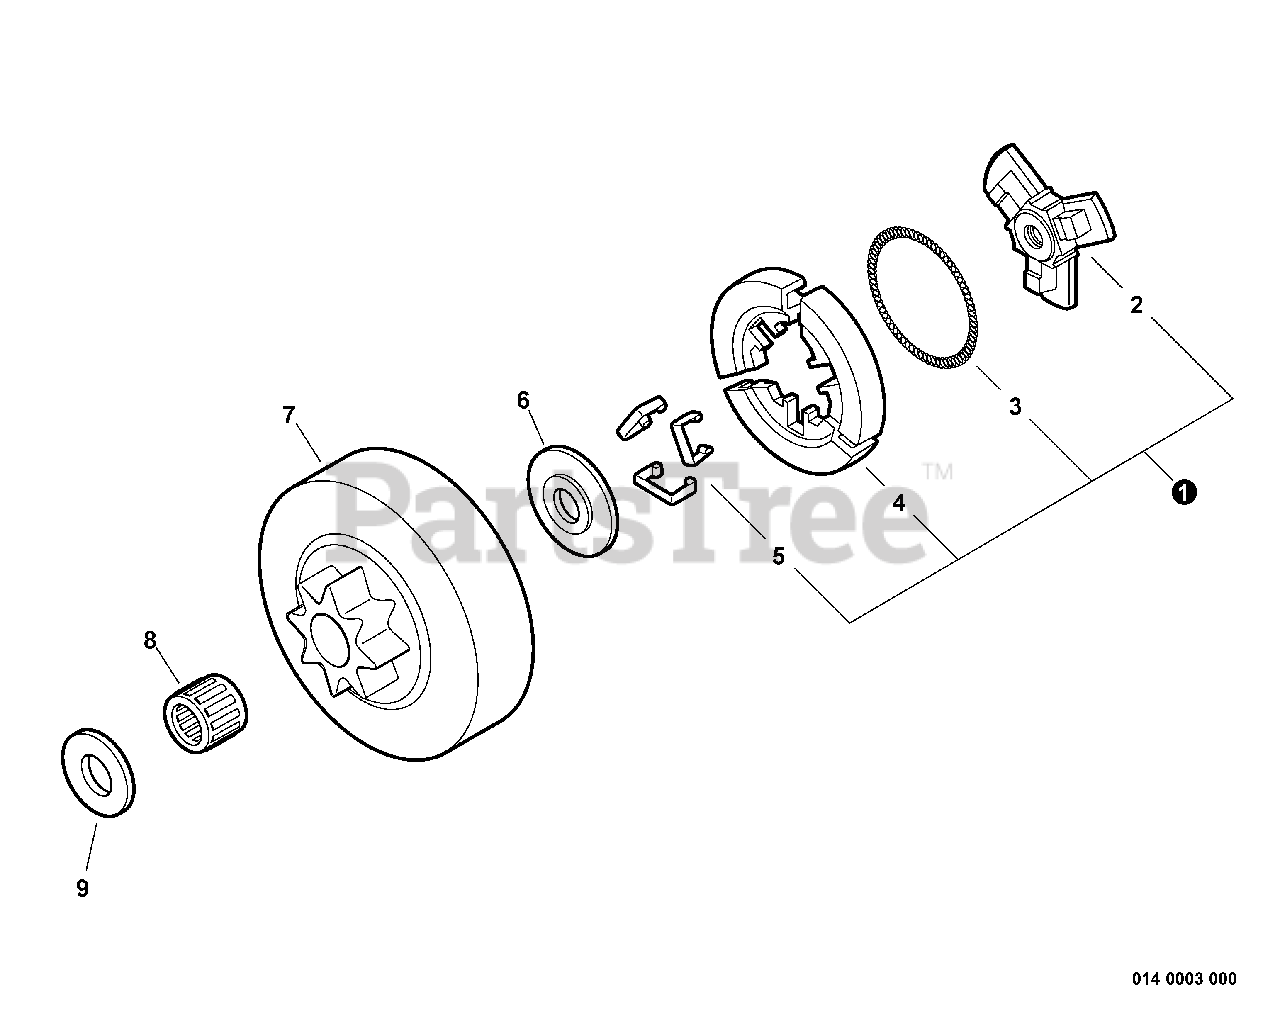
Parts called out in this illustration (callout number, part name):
1	CLUTCH ASSY
2	HUB, CLUTCH
3	SPRING, TORSION
4	SHOE SET, CLUTCH (3PCS)
5	SPRING, FLAT
6	PLATE, CLUTCH
7	DRUM, CLUTCH 3/8"
8	BEARING, NEEDLE 10×13×10
9	WASHER 10.2×24.5×1.2
